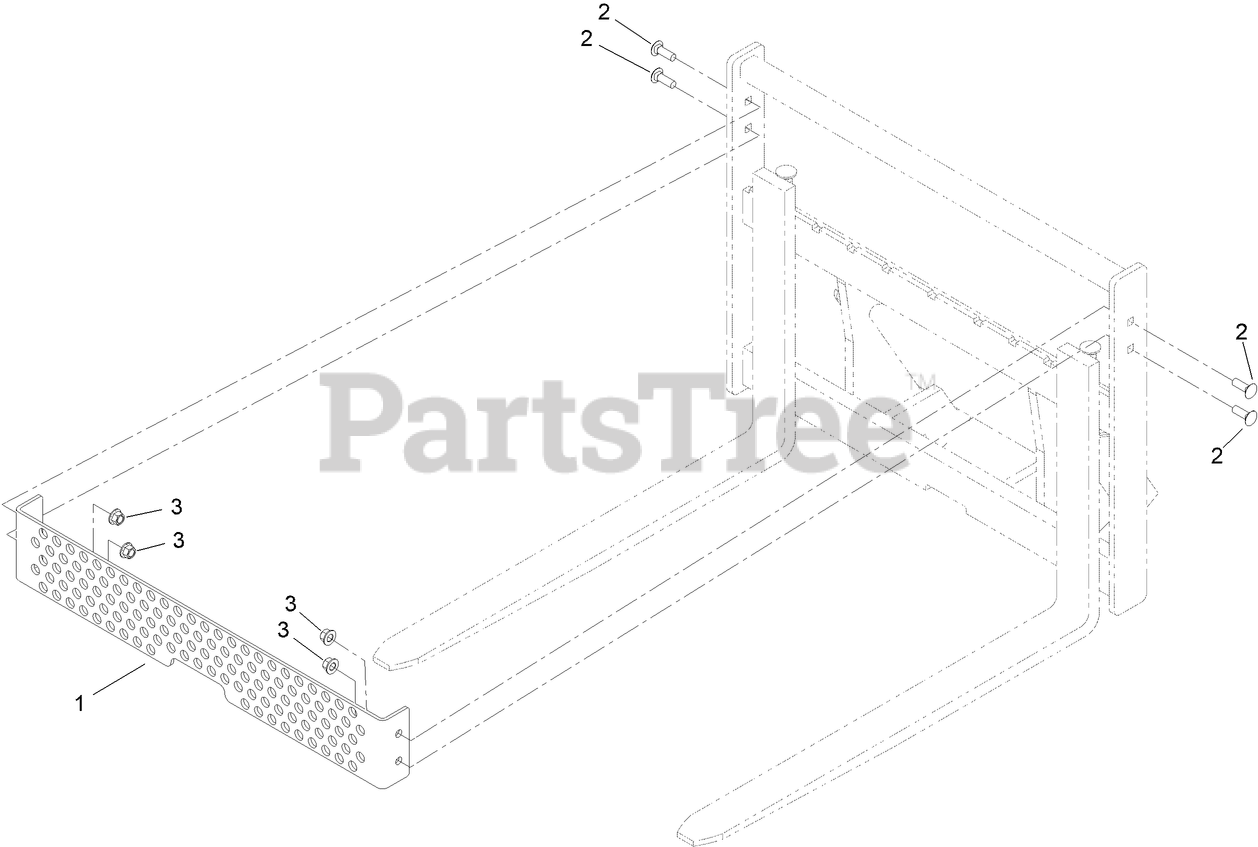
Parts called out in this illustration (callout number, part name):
1	PLATE-GUARD,BRICK
2	SCREW-CARR
3	NUT-LOCK
